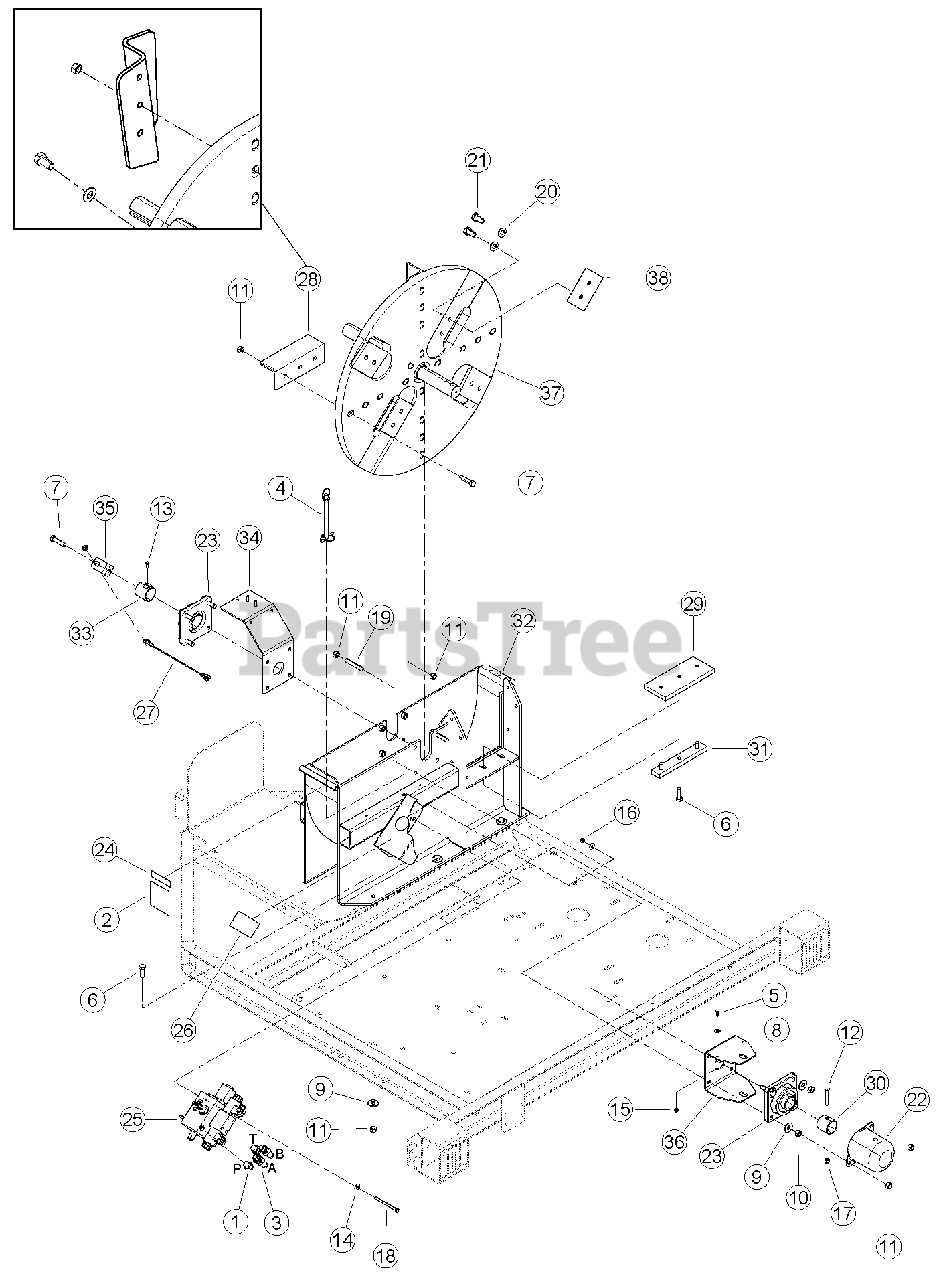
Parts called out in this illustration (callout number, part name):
1	ADAPTER, -8 MORING / -8 MJIC
2	DECAL, 112 DB (CE COMPLIANT MODELS)
3	ADAPTER, -8 MORB / -8 MJIC 45 DEG.
4	PIN, HITCH 1/2 X 6-1/2 W/LYNCH
5	BOLT, 1/4 X 3/4 HEX HD GR5 ZP
6	BOLT, 1/2 X 1-1/2 HEX HD GR5 ZP
7	BOLT, 1/2 X 2 HEX HD GR5 ZP
8	WASHER, 1/4 FLAT ZP
9	WASHER, 1/2 FLAT ZP
10	NUT, 1/2 HEX NC ZP
11	NUT, 1/2 CENTERLOCK GRB ZP
12	BOLT, 3/8 X 2-1/2 HHCS GR5 ZP
13	SCREW, 5/16-18 X 5/8 SQ HD SET
14	WASHER, 5/16 FLAT ZP
15	NUT, 1/4 NE NYLOCK ZP
16	NUT, 5/16 NE NYLOCK ZP
17	NUT, 3/8 NE NYLOCK ZP
18	BOLT, 5/16 X 4 HHCS GR5 ZP
19	STUD, 1/2-13 X 3 LG B7 ZP
20	WASHER, 5/8 SAE HARDENED
21	BOLT, M16 X 2 X 30 HEX HD W/PATCH
22	CAP, LARGE SHAFT
23	BEARING, 1-3/4 4 BOLT FLANGE
24	DECAL, 74950S INFO (CE COMPLIANT MODELS)
25	ASSEMBLY, CHIPPER VALVE (SEE VALVE ASSEMBLY FOR SERVICE PARTS)
26	DECAL, FEED SPEED
27	SENSOR, M12 PNP PROXIMITY
29	PLATE, CHIPPER BOTTOM
30	COLLAR, CHIPPER LOCK
31	SPACER, CHIPPER ANVIL
32	WELDMENT, CHIPPER BOTTOM
33	WELDMENT, SPACER
34	WELDMENT, GUARD SUPPORT
35	BRACKET, SENSOR SHORT MOUNT
36	BRACKET, DISK LOCK
37	ASSEMBLY, 9 IN. CHIPPER DISK
